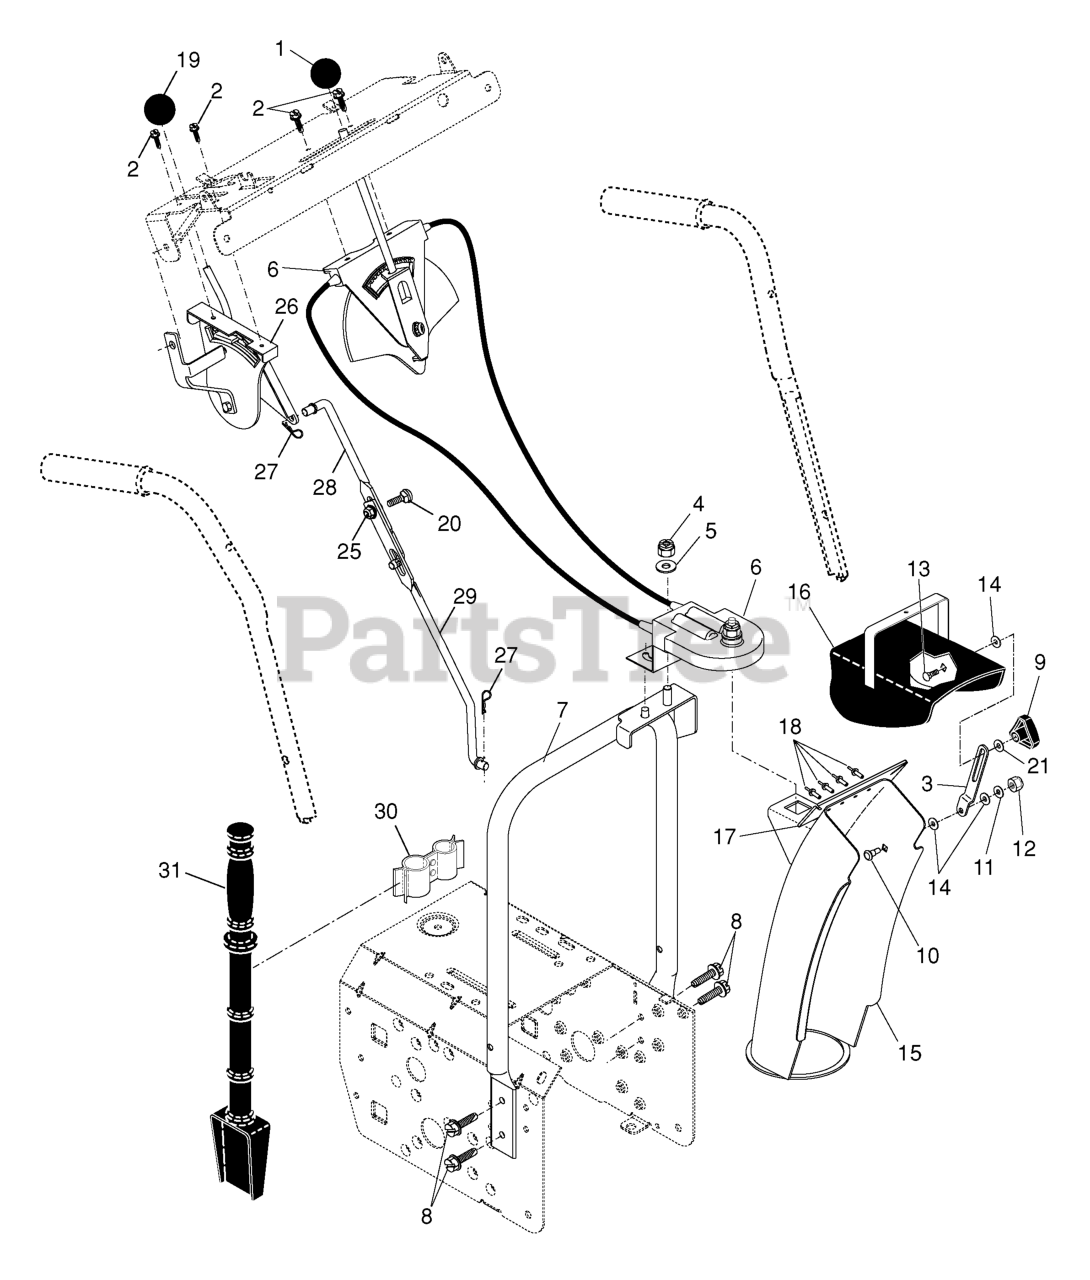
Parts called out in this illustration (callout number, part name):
1	KNOB, LEVER
2	SCREW #10-24 X 5/8
3	STRAP, CHUTE
4	NUT
5	WASHER
6	CONTROL ASSY, CHUTE ROTATER
7	SUPPORT CHUTE ROTATER
8	SELF-TAPPING SCREW 5/16-18X3/4
9	KNOB.SKID.PLATE
10	SHOULDER BOLT
11	WASHER
12	LOCKNUT.NYLOC.1/4-20
13	BOLT
14	WASHER, NYLON FRICTION
15	CHUTE ASSY
16	DEFLECTOR.WELDMENT.PNT.ORANGE
17	SEAL, DEFLECTOR
18	RIVET BLIND
19	RP KNOB, SPEED CONTROL LEVER
20	BOLT
21	WASHER.20X8.5
25	NUT.FLANGE.5/16
26	HEAD ASSY SPEED
27	SPRING RETAINER
28	ROD, UPPER SPEED CONTROL
29	ROD, LOWER SPEED CONTROL.SNOW
30	CLAMP.ASM.CLEANOUT.TOOL.SNOW
31	CLEAN OUT TOOL
